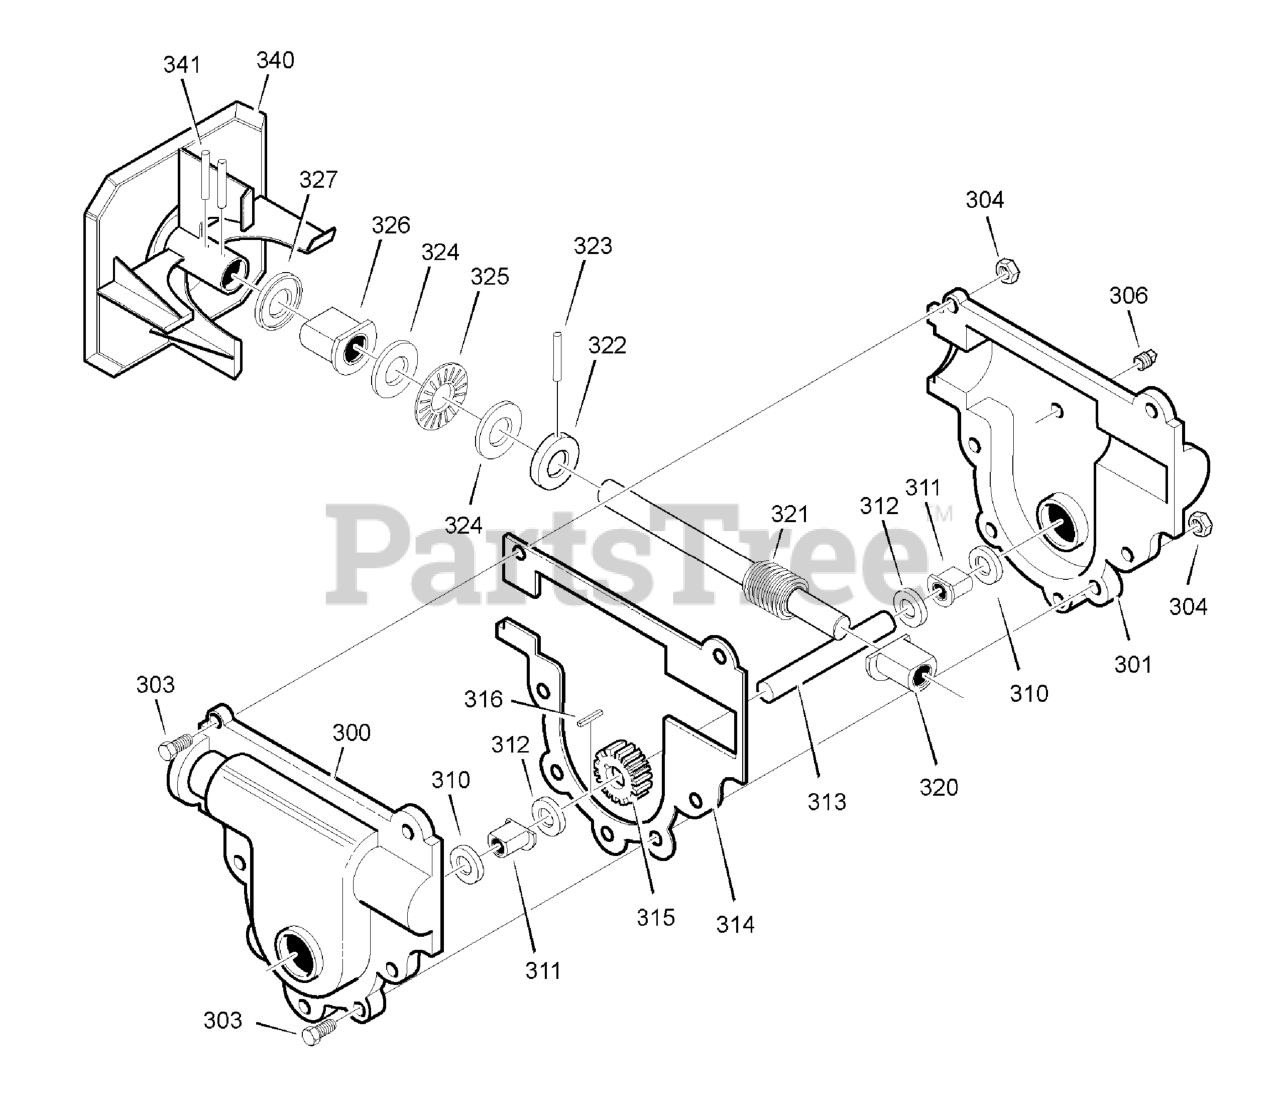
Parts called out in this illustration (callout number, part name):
300	CASE, GEAR, RH
301	CASE, GEAR, LH
303	SCREW, 1/4-20 X 0.75
304	NUT,1/4-20
306	SCREW, 3/8-16 X 0.50
310	SEAL, OIL
311	BEARING, FLANGE
312	WASHER, FLAT
313	SHAFT, AUGER OUTPUT
314	GASKET, GEAR BOX
315	GEAR, WORM
316	KEY, WOODRUFF #61
320	BEARING, FLANGE
321	SHAFT, AUGER INPUT (IMPELLER)
322	COLLAR, THRUST
323	PIN, SPRING
324	WASHER, FLAT
325	BEARING, ROLL
326	BEARING, FLANGE
327	SEAL, OIL
341	PIN, SPRING
